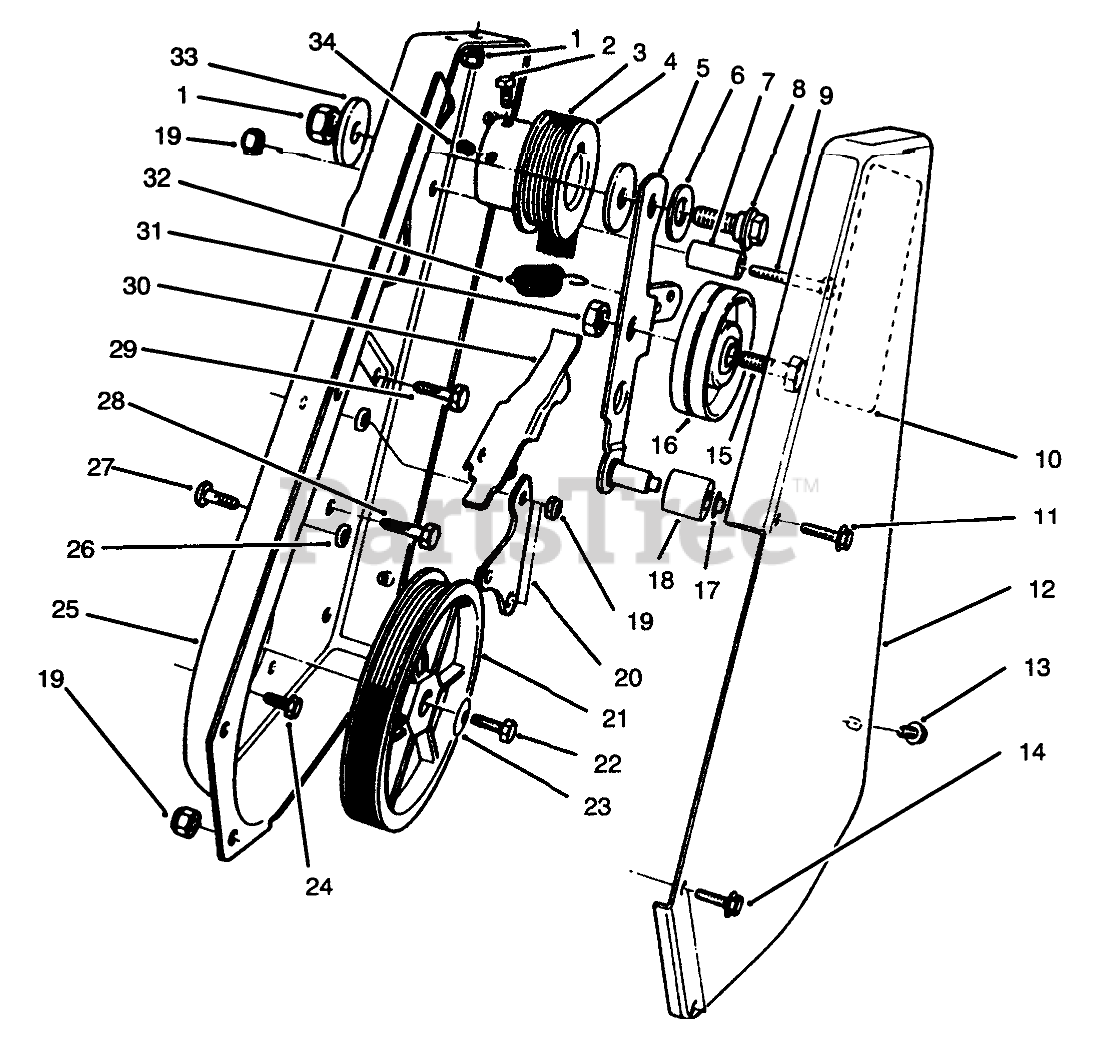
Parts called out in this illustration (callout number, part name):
1	NUT-LOCK, NI
2	SCREW-SQH
3	BELT - DRIVE
4	ENGINE PULLEY
5	Idler Arm Assembly (Incl. Ref. #17 & 18)
6	WASHER
7	SLEEVE-GUIDE, BELT
8	SCREW-SHOULDER
9	SCREW-HH
10	DECAL
11	SCREW-HWH, TAP
12	Cover-Drive
13	SCREW
14	SCREW-HWH
15	SCREW-HH
16	PULLEY-IDLER
17	NUT-PUSH
18	ROLLER-BRAKE
19	NUT-LOCK, NI
20	PIVOT PLATE ASM
21	ROTOR PULLEY ASY
22	SCREW-HH
23	WASHER-BELLEVILLE
24	SCREW-SHH
25	Sideplate-LH
26	SPACER-PLATE, PIVOT
27	SCREW-HSBH
28	SCREW-HH
29	SCREW-HH
30	BRAKE-ARM
31	NUT-LOCK, CONE
32	SPRING-EXTENSION
33	WASHER-PIVOT
34	SCREW-HSH
